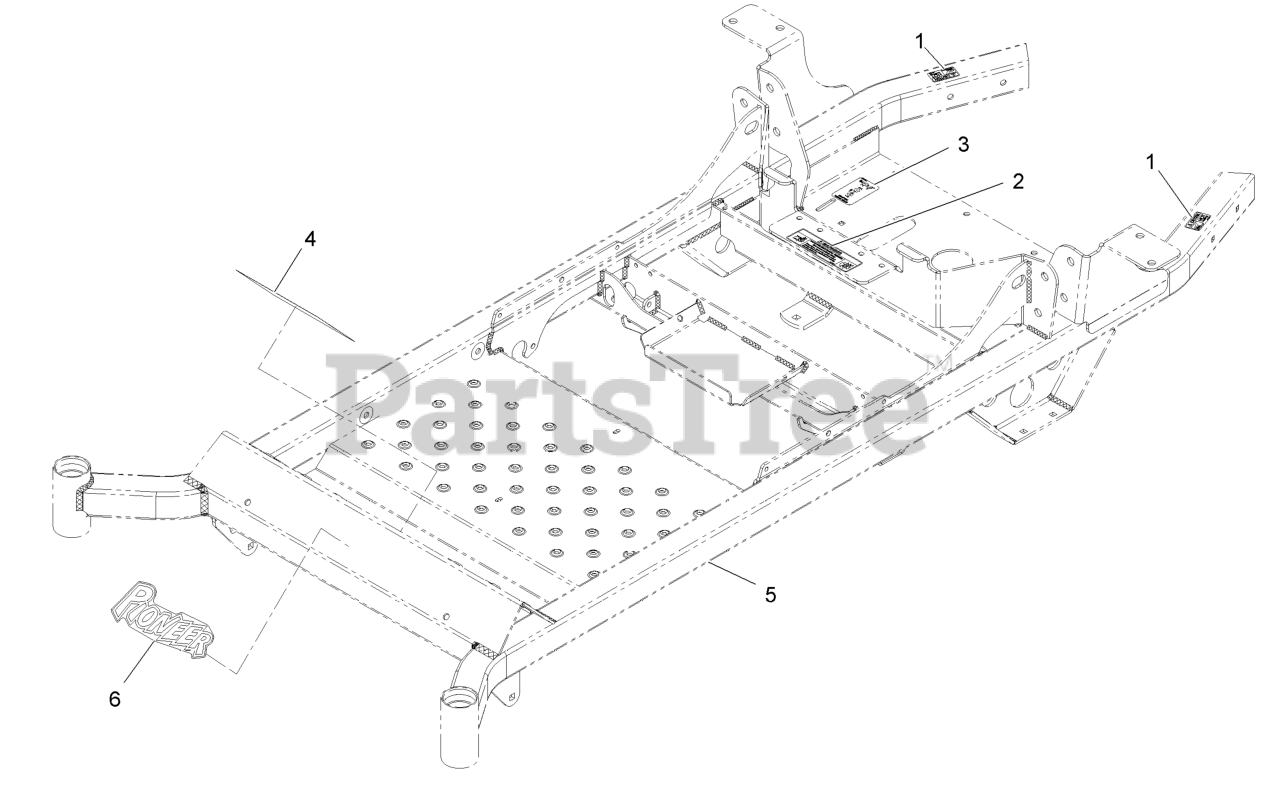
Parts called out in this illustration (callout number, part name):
1	DECAL-CAUTION
2	DECAL,BELT DRIVE
3	DECAL,DRIVE RELEASE
4	DECAL-SLOPE
6	DECAL-PIONEER LOGO
